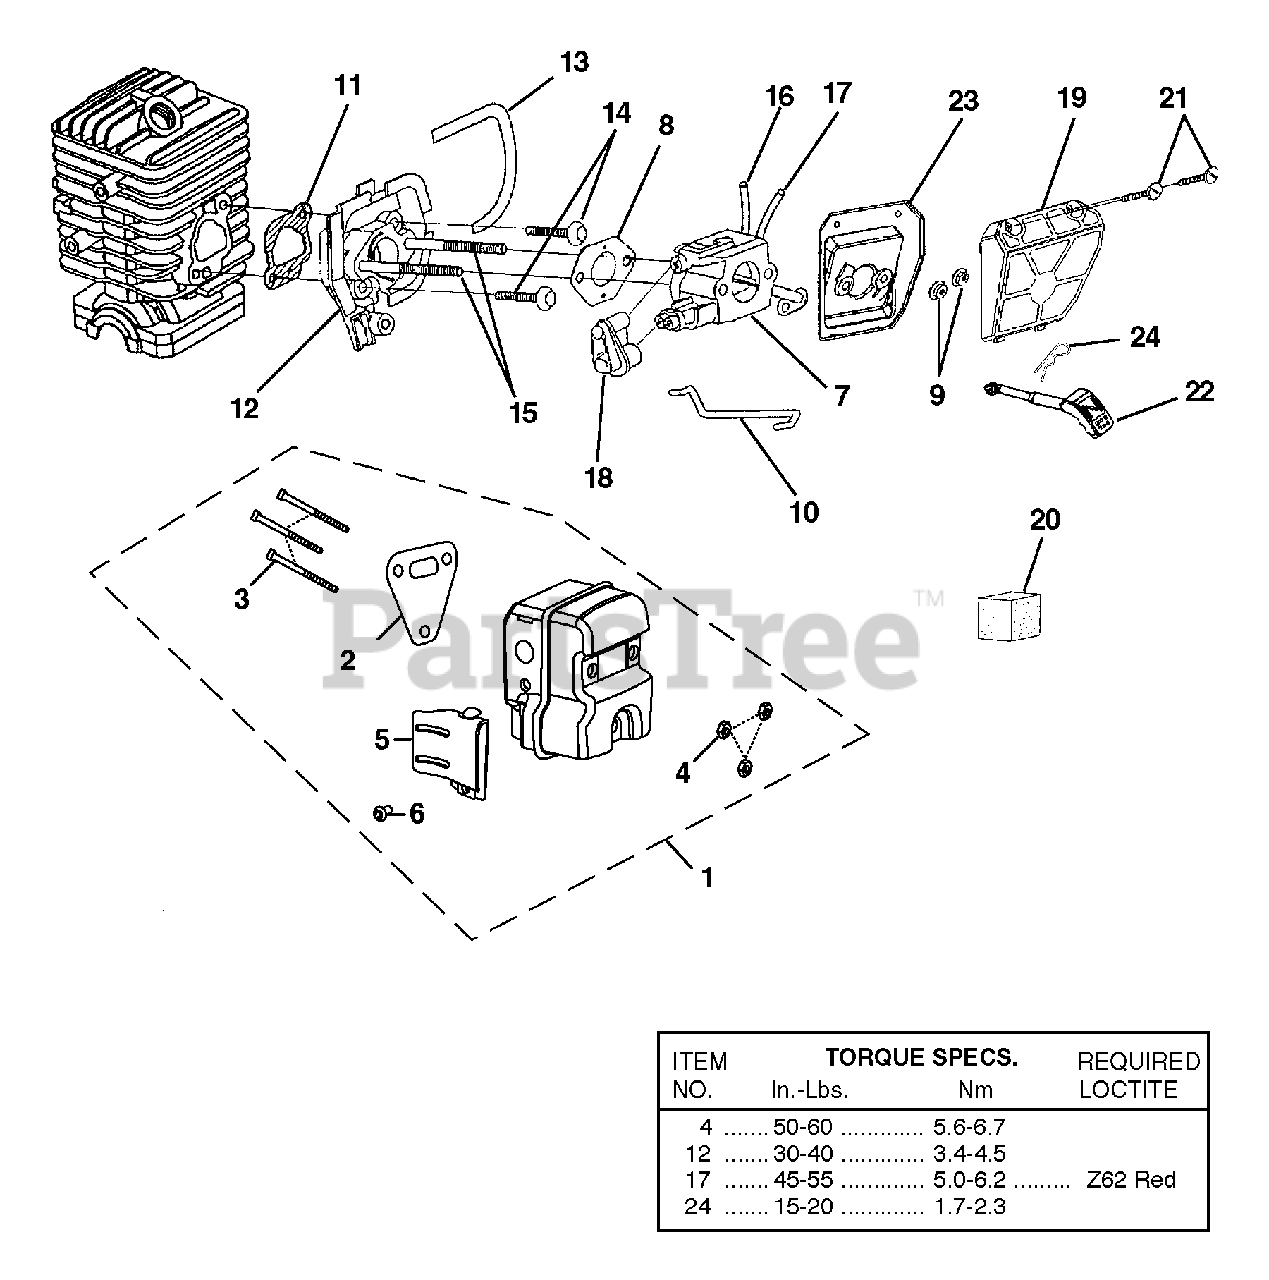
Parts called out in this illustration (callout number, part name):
1	Muffler Kit
2	Muffler Gasket
3	Screw-Square Hd.
4	Nut-Locking Hex (10-32)
5	Deflector, Muffler
6	Screw (8-32 X .312 Pan Hd.)
7	Carburetor Assembly
8	Carburetor Gasket
9	Flange Nut (10-24)
10	Throttle Wire
11	Gasket, Heat Dam
12	Carburetor Spacer
13	Seal, Heat Dam
14	Screw, Truss Hd. Taptite (10-24 x 7/8")
15	Screw, Carburetor
16	Fuel Line (Tank to Carburetor 8 1/2")
17	Fuel Line (Carburetor to Purge Bulb 2")
18	Carburetor Grommet
19	Air Filter Cover
20	Pre Filter (In engine housing)
21	Screw-Slotted Pan Hd. (8-16 x 5/8")
22	Rod, Choke
23	Air Filter Plate
24	Spring Clip (Choke Rod)
